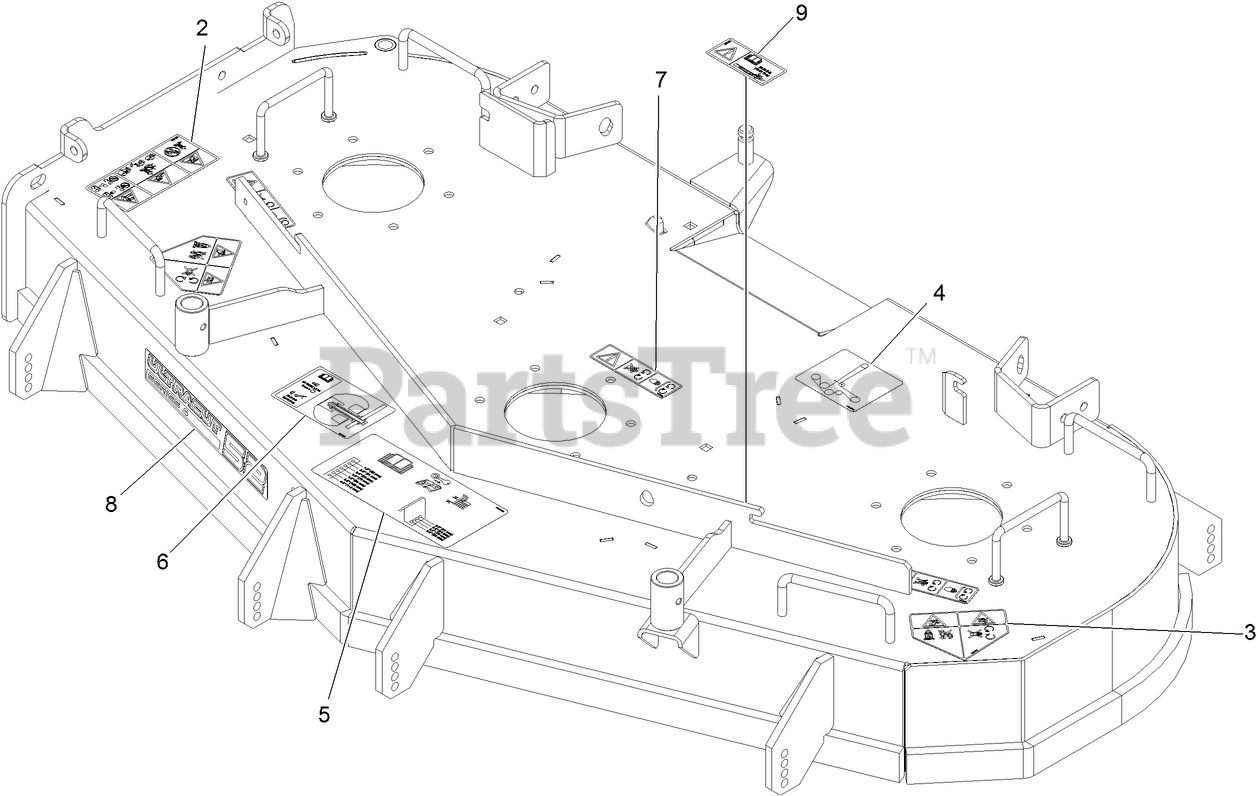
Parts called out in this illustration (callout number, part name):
2	DECAL-WARNING THROWN OBJ
3	DECAL-DANGER
4	DECAL-BELT ROUTING
5	DECAL-ANTI-SCALP
6	DECAL-ROLLER MOUNTING
7	DECAL-COVER, MISSING
8	DECAL, 524
9	DECAL-TORQUE, BOLT
